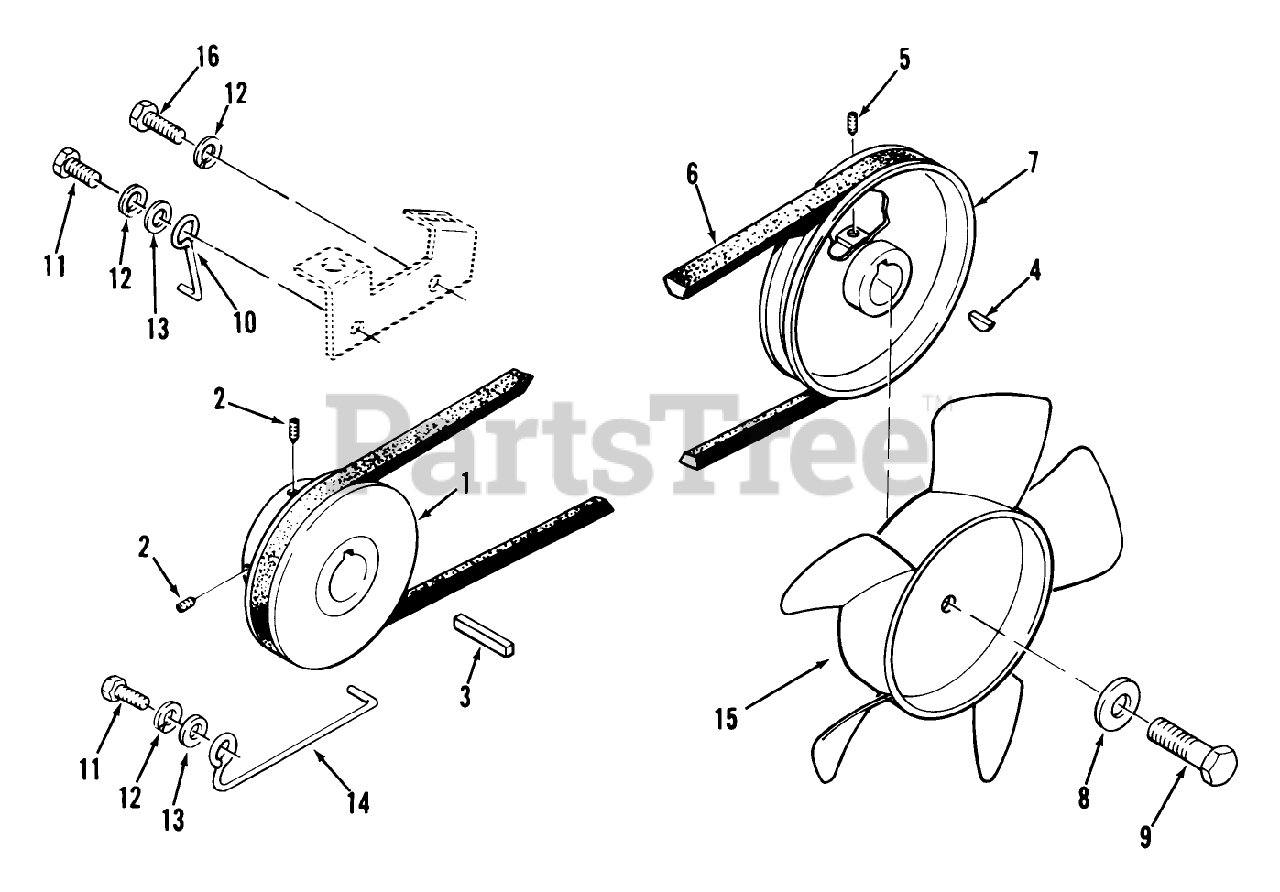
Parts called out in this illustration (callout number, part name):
1	PULLEY
6	V BELT
7	PULLEY-TRANSMISSION
12	LOCKWASHER
13	WASHER
